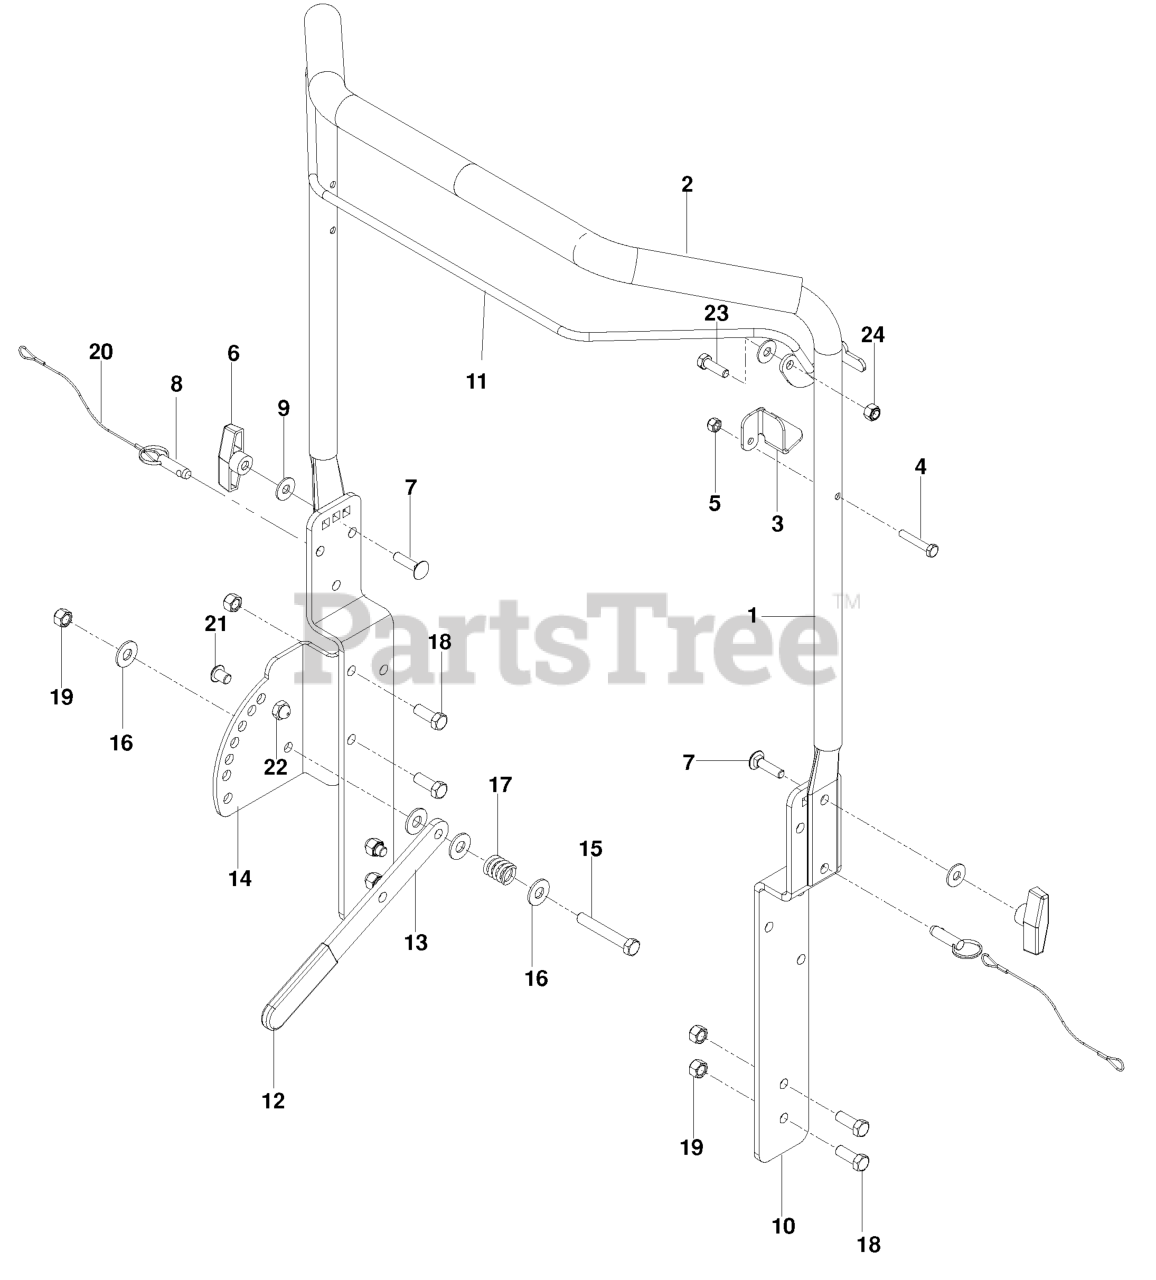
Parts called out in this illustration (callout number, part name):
1	HANDLE GRAY
3	CABLE TAB POWER RAKE
4	SCW 1/4-20 X 1-1/2 HEX
5	NUT.1/4-20.HEX.NYLOC.ZD
7	BOLT, CARRIAGE 5/16X1-1/4
8	DETENT PIN RAKE/DT
9	WASHER 5/16 FLAT
10	HANDLE SIDE GREY
11	BAIL - ORANGE
13	LEVER, PLATED
14	HEIGHT ADJUSTMENT PLATE
15	HCS 3/8C X 2
16	WASHER 3/8 FLAT
17	COMPRESSION SPRING
18	HCS 3/8-16X1.GRD.5.ZD
19	NUT 3/8-16 NYLOC
21	BLT 3/8-16 X 1/2 BTN HD BLK SP
22	NUT 3/8-16 ACORN HEX
23	HCS 5/16C X 1
24	NUT 5/16 NYLOC
